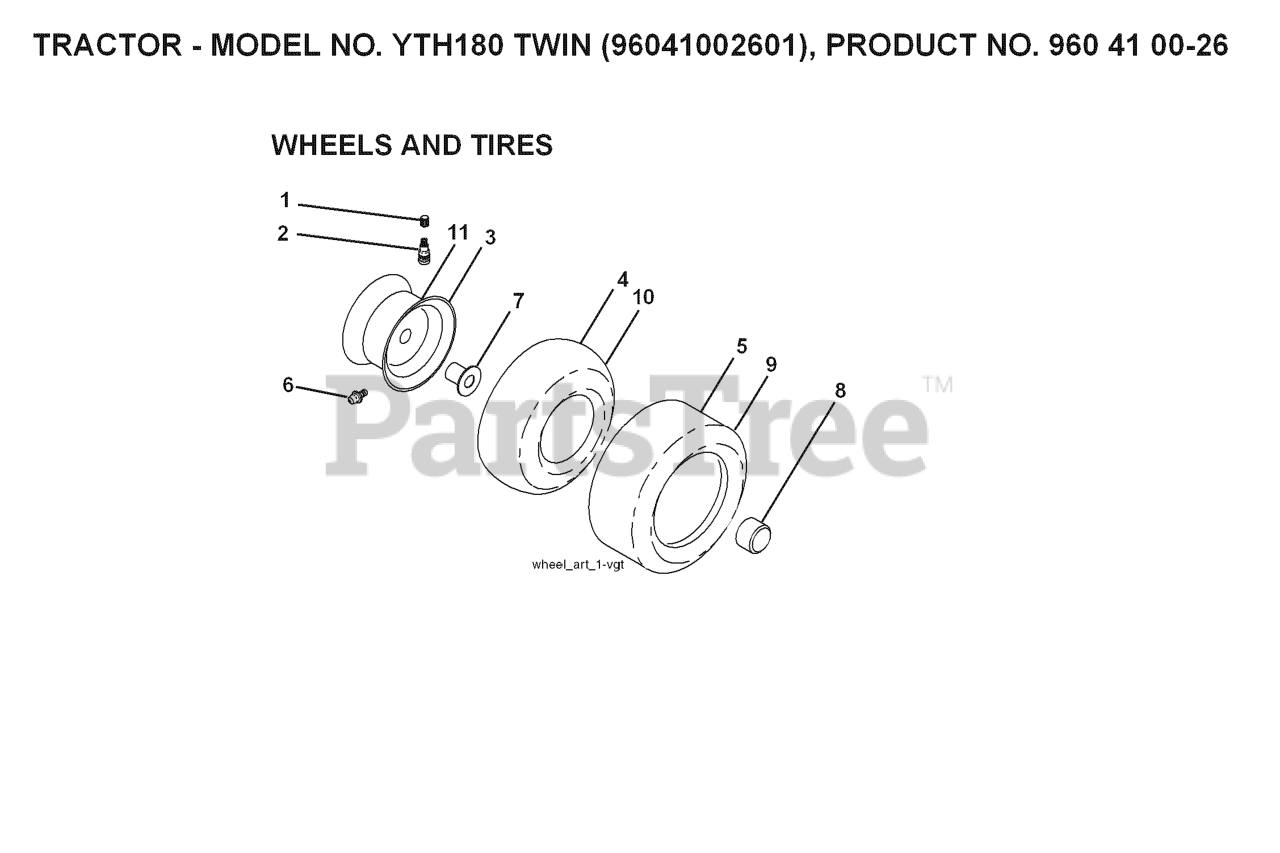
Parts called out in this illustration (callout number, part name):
2	VALVE STEM LT
3	RIM ASM 6" FRONT SILVER
4	TUBE.5.3/4.5/6
5	TIRE HEAVY DUTY
6	FITTING LT
7	BEARING T
8	CAP, AXLE BLK
9	TIRE.TS.20X10-8
10	TUBE
11	RIM ASM 8" REAR SILVER
